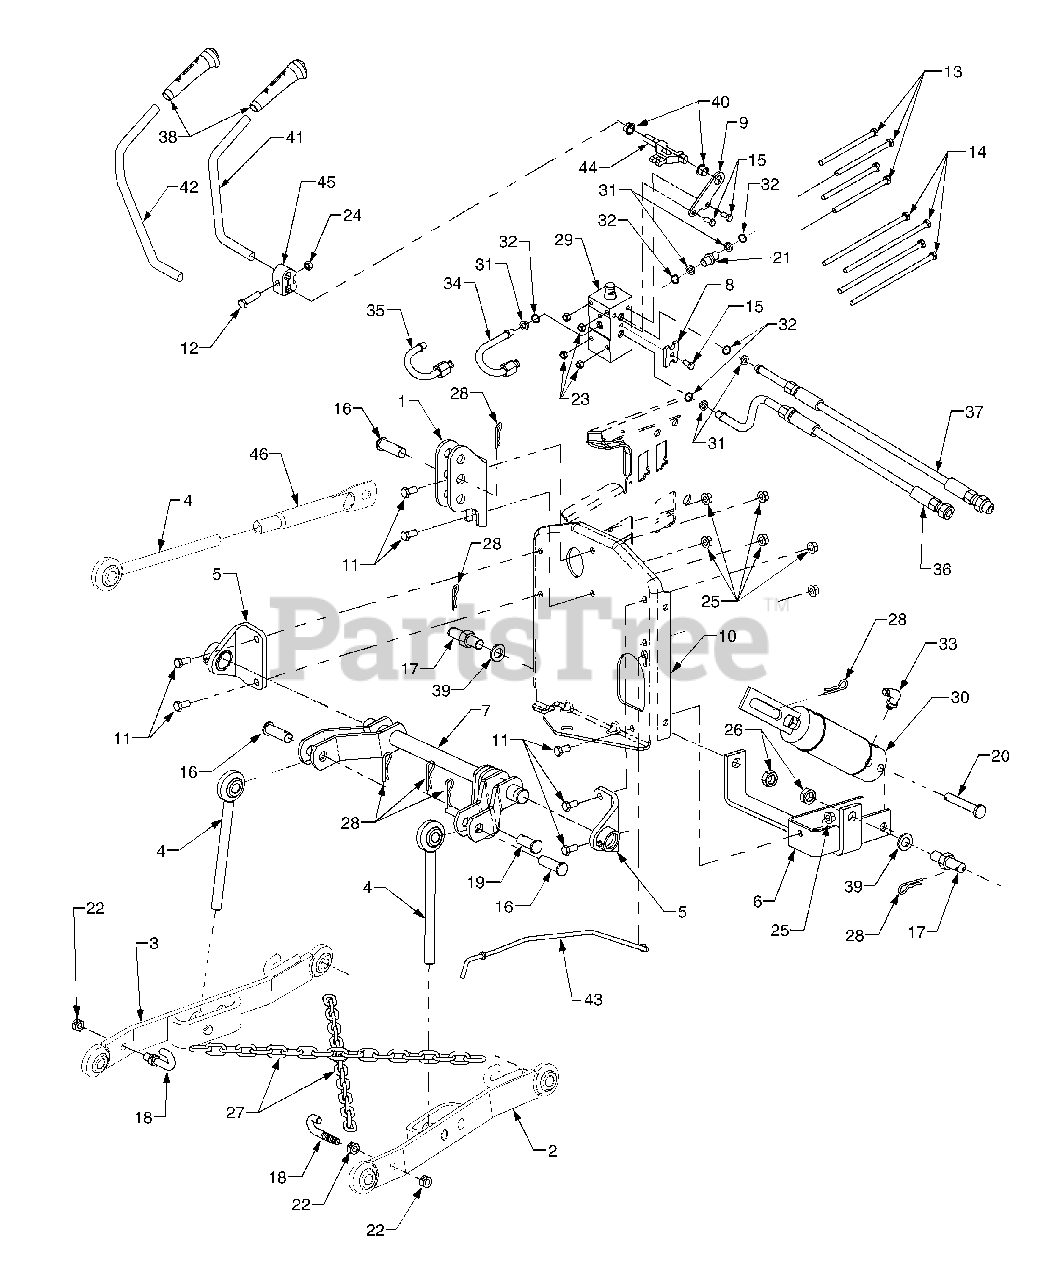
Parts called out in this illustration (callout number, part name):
1	Hitch Bracket
2	Link Ass'y., Lower - RH
3	Link Ass'y., Lower - LH
4	Link, Adjustment
5	Bracket, Rockshaft
6	Brace Assembly, Hitch
7	Rockshaft Assembly,
8	Clamp, Double Valve
9	Bracket, Lift Valve
10	Plate, Hitch 3 Point
11	Screw, Hex Cap 3/8-16 x 1.00 GR 5
12	Screw, Hex Cap 5/16-18 x 1.25 GR5
13	Screw, Hex Cap 1/4-20 x 4.0 GR5
14	Screw, Hex Cap 1/4-20 x 6.0 GR5
15	Screw, Hex Cap 1/4-20 x .5 GR5
16	Pin, Clevis, .624 Dia.
17	Pin, Link Clevis
18	Hook, 7/16-14 Thrd.
19	Pin, Clevis, .62 x 1.34
20	Pin, Clevis, .5 x 3.2
21	Adapter, Valve
22	Nut, Hex Lock, 7/16-14
23	Nut, Hex Insert Lock, 1/4-20
24	Nut, Hex Insert Lock, 5/16-18
25	Nut, Hex Flange Lock, 3/8-16
26	Nut, Hex Lock, 5/8-18
27	Chain, 18.99 Lg
28	Pin, Internal Cotter
29	Valve Assembly, Hydraulic Lift
30	Cylinder Assembly, Lift
31	O-Ring, Backup, .327 x .433 x .05
32	O-Ring, .301 ID x .070 Dia
34	Tube, Hydro Return, Aux. Valve #1
35	Tube, Hydro Return, Aux. Valve #2
36	Hose, 3 Point Lift
37	Hose, 3 Point Return
38	Knob, Valve Handle
39	Washer, Flat, .640 x 1.12 x .125
40	Bearing, Nylon Flange, .5 ID
41	Handle, Hydraulic Valve Aux. #1
42	Handle, Hydraulic Valve Aux. #2
43	Rod, Pump Bypass
44	Link, Lift
45	Clamp, Handle
